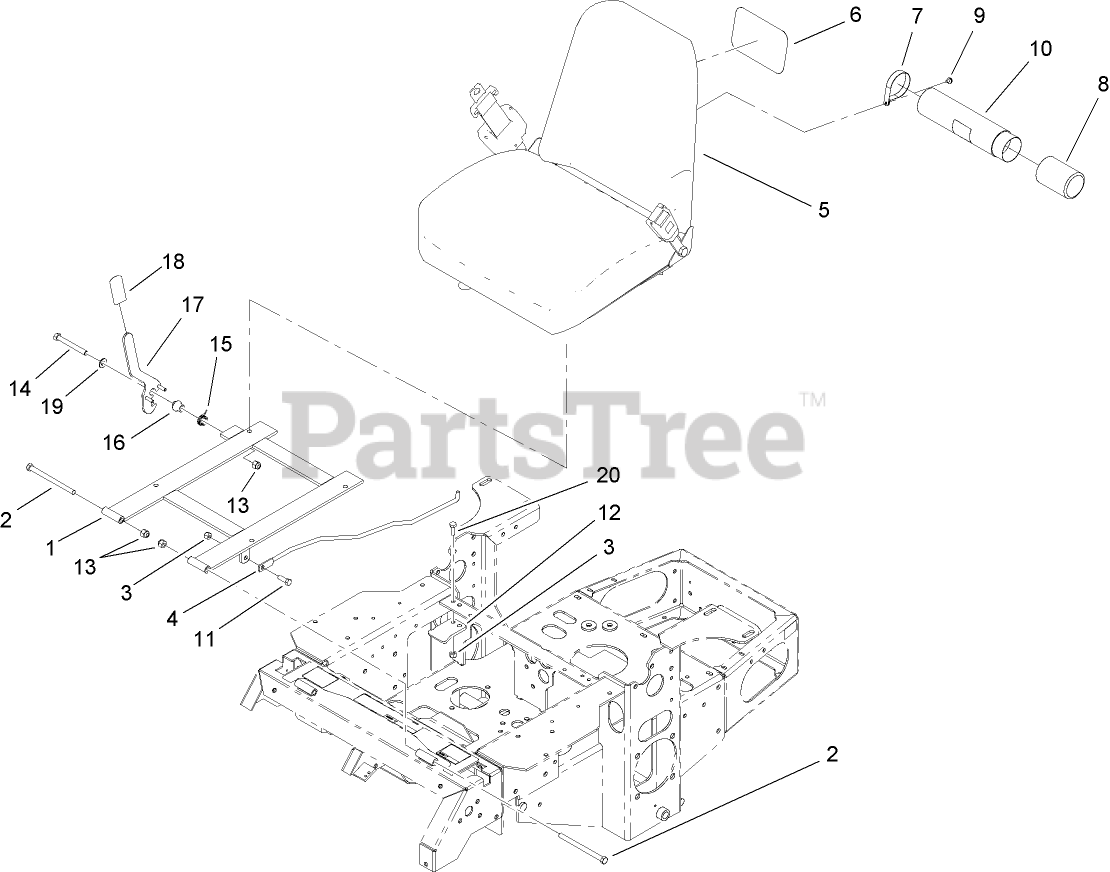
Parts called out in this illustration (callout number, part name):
1	SEAT SUPPORT FRAME ASM
2	SCREW-HH
3	NUT-LOCK, NI
4	ROD-RETAINER, SEAT
5	SEAT ASM
6	DECAL
7	CLAMP-R
8	CAP-HOUSING
9	SCREW-HWHTF
10	TUBE-MANUAL
11	SCREW-HH
12	CATCH-LATCH, SEAT
13	NUT-LOCK, NI
14	SCREW-HH
15	SPRING-TORSION
16	BUSHING-LATCH, SEAT
17	LATCH ASM
18	GRIP-LEVER
19	WASHER-FLAT
20	SCREW-HH
